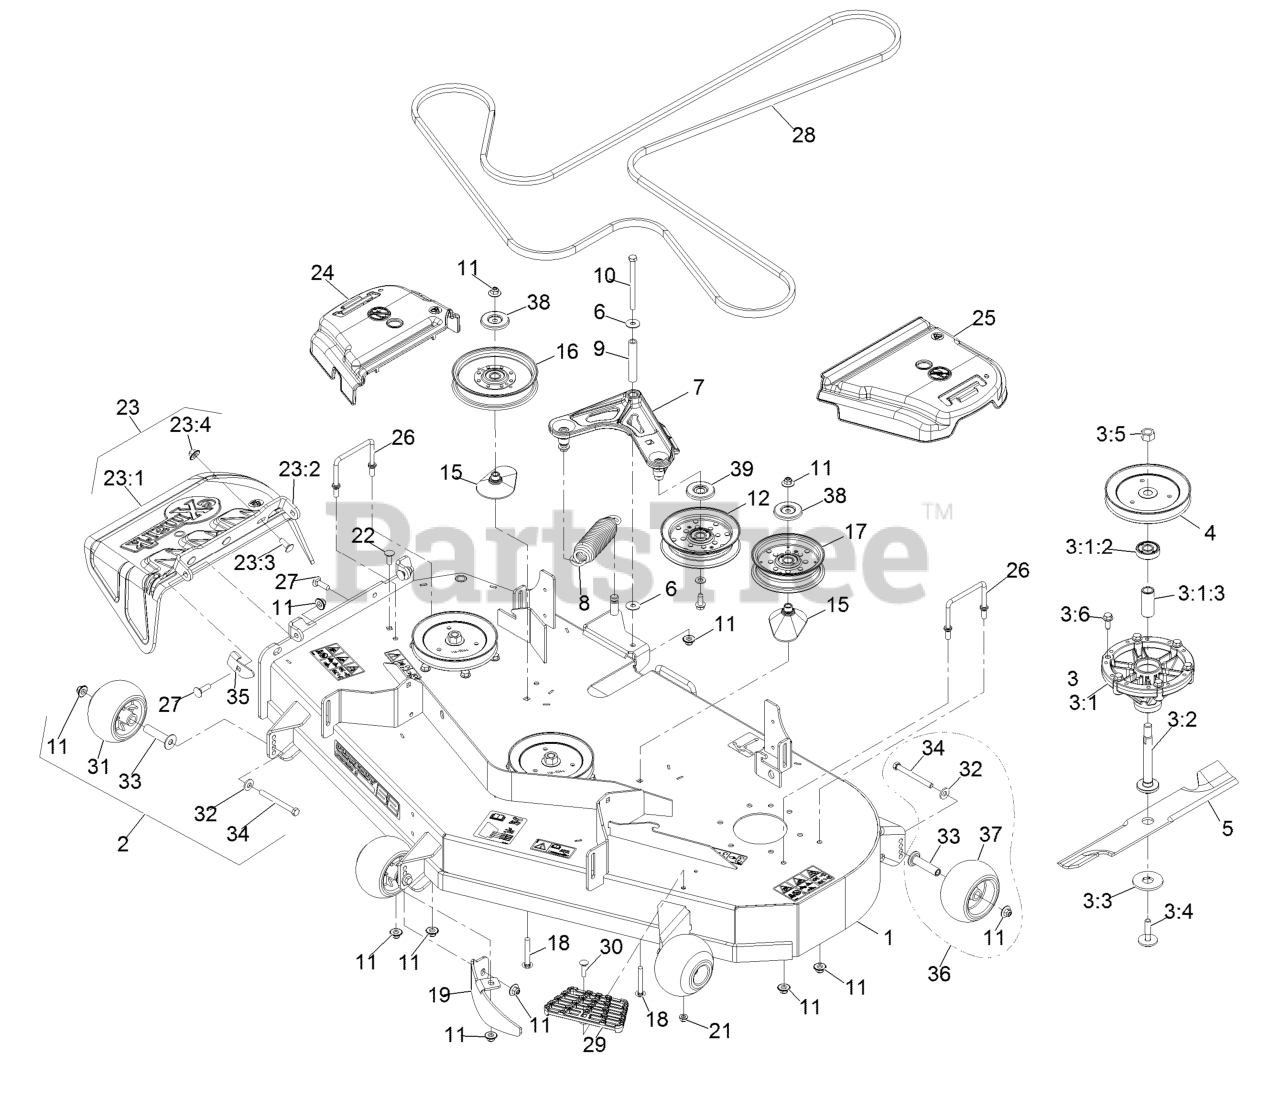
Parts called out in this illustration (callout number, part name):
1	ASM-Deck W/Decals 523
2	Kit, Anti-Scalp Roller
3	ASM, Cutter Housing Complete
3:1	ASM-Cutter Housing
3:1:2	Bearing
3:1:3	Spacer-Bearing
3:2	Spindle-Hex Pilot
3:3	Washer-Hex Blade Drive
3:4	Bolt-Blade, Sem
3:5	Nut-Hex
3:6	Screw-Forming, Thread
4	Sheave,Blade Drive 6.50
5	Blade, Solid
5	Blade, Low Lift
5	Blade, Mulching
5	Blade-Notched
5	Blade-Extreme 2, 18.00"
7	Idler Arm ASM
8	Spring-Extension
9	Bushing
10	Screw-HH
11	Nut-Flange, NI
12	Idler-Pulley, Flat
15	Spacer-Pulley
16	Idler-Pulley, Flat 6.00X1.00
17	Idler-Pulley, Flat 5.00X1.31
18	Screw-CARR
19	Baffle-Dogleg, Lze-Pns-52
21	Nut-HF, NI
22	Screw-CARR
23	ASM,Discharge Chute
23:1	Chute, Discharge
23:2	Bracket,Discharge Chute
23:3	Screw-CARR
23:4	Nut-Flange, NI
24	Cover-Belt, RH
25	Cover-Belt, LH
26	Wireform-Cover
27	Bolt-CARR
28	Belt-V
29	Step-Deck
30	Screw-CARR
31	Roller-Anti-Scalp
32	Washer-Belleville
33	Axle, Roller
34	Screw-HH
35	Stop-Discharge Chute
36	Kit-Antiscalp Roller
37	Roller-Scalp, Anti
38	Shield-Dust
39	Shield-Guard, Dust
